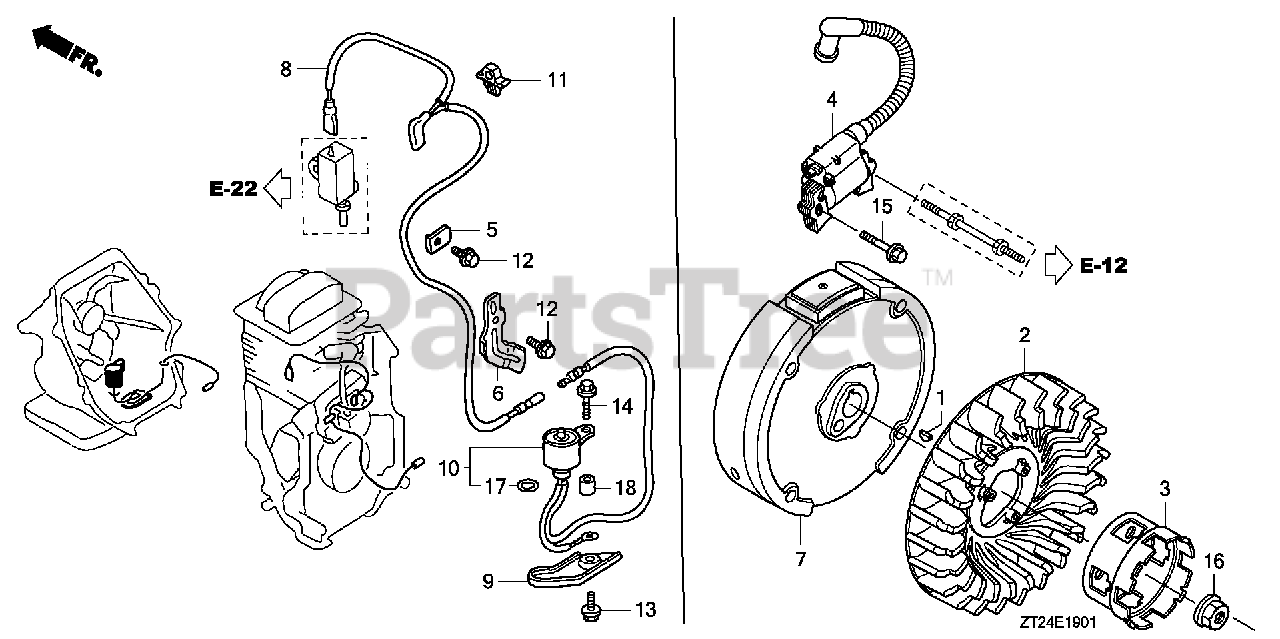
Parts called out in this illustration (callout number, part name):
1	KEY, SPECIAL WOODRUFF (25X18)
2	FAN, COOLING
3	PULLEY, STARTER
4	COIL ASSY., IGNITION (TOYO)
5	CLAMP, STOP SWITCH WIRE
6	CLAMP, WIRE
7	FLYWHEEL
8	WIRE, STOP SWITCH
9	PROTECTOR, SWITCH
10	SWITCH, OIL LEVEL
11	HOLDER, STOP SWITCH WIRE
12	BOLT, FLANGE (6X12) (CT200)
13	BOLT, FLANGE (6X14) (CT200)
14	BOLT, FLANGE (6X28) (CT200)
15	BOLT, FLANGE (6X23) (CT200)
16	NUT, SPECIAL (14MM)
17	O-RING (11.8X2.4)
18	COLLAR (6.6X13.8X14.5)
